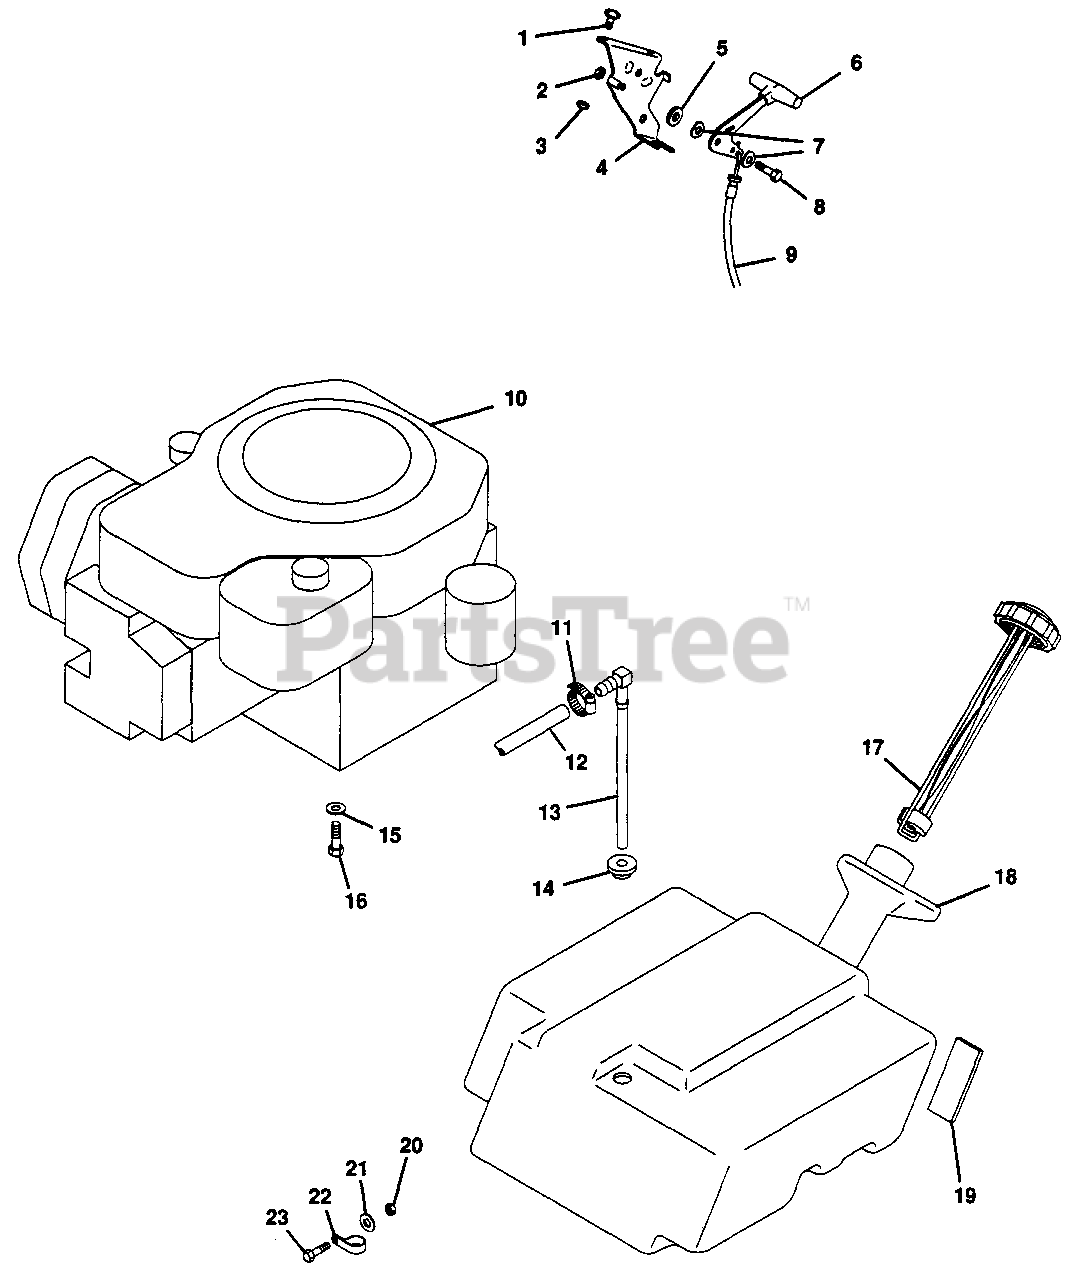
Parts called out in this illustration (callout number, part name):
1	Screw, Mach. 10-24 x .625 PHD
2	Nut, Lock 1/4-28
3	Nut, Lock 10-24
4	Bracket, Mounting L.H.
5	Washer, Flat .281 x .625 x .065
6	Assembly, Knob and Lever
7	Washer, Spring
8	Bolt, Hex 1/4-28 x .625
9	Assembly, Conduit
10	Engine, 12.5 HP Kohler
10	Engine, 14 HP Kohler
11	Clamp, Hose
12	Line, Fuel .5 OD x .25 ID
13	Fitting, Tank
14	Bush., .563 x 1.06 x .688
15	Washer, Lock 5/16 Reg.
16	Bolt, Hex M8 x 1.25 25 mm
17	Fuel Gauge and Cap
18	Tank, Fuel
19	Pad, Gas Tank
20	Nut, Lock 5/16-18
21	Washer, Flat .313 x .875 x .065
22	Clamp, Steel .625
23	Bolt, Hex 5/16-18 x 1.00
